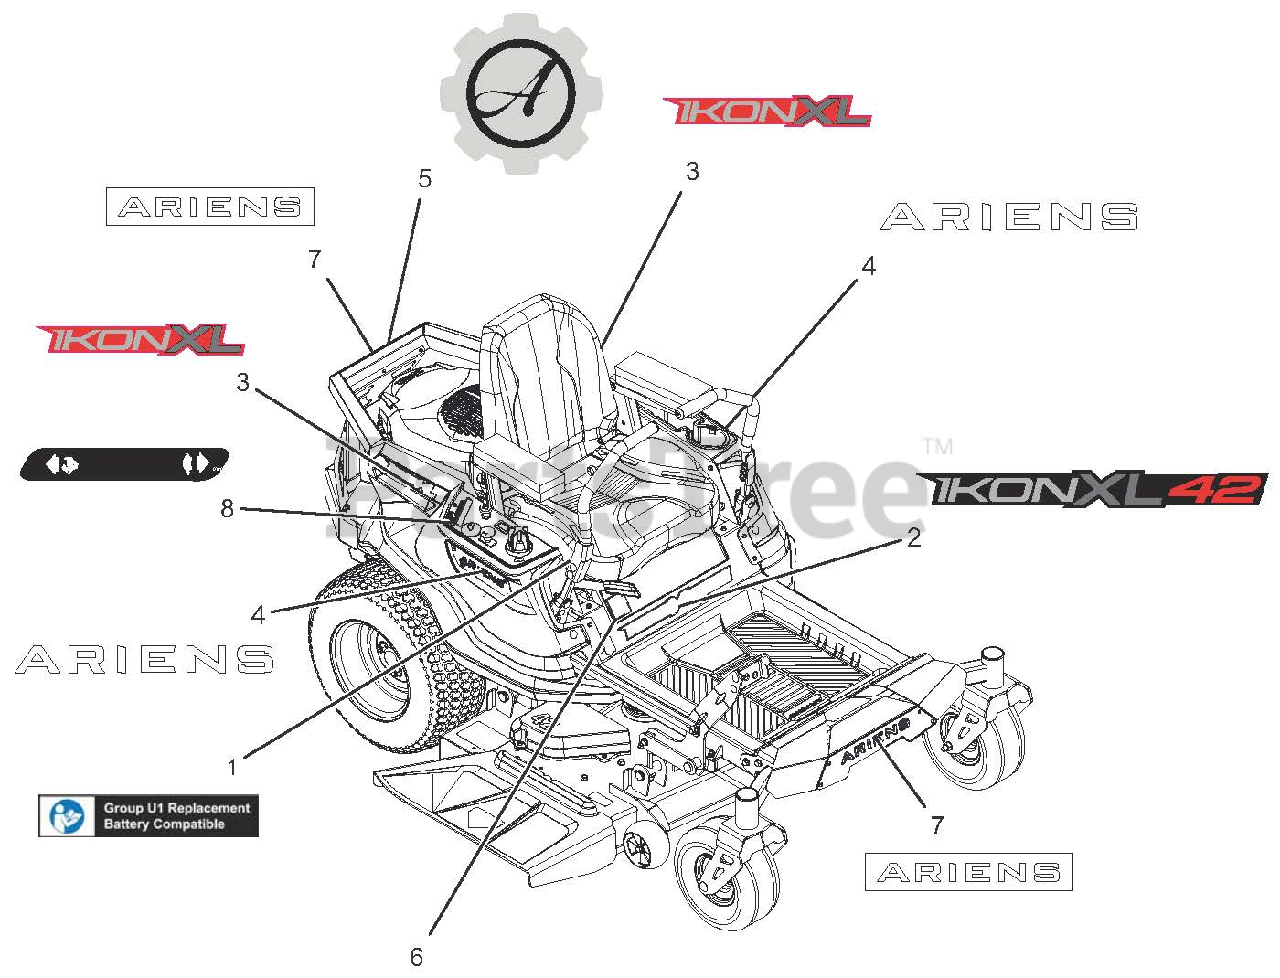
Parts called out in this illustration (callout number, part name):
1	DECAL, U1 BATTERY REPLACEMENT
2	DECAL, IKON-XL 42"
3	DECAL, IKON-XL
4	DECAL, ARIENS (6.50")
5	DECAL, ARIENS-GEAR BADGE
6	DECAL, MADE IN USA
7	DECAL - ARIENS 9.625"
8	DECAL, DASH DECAL
